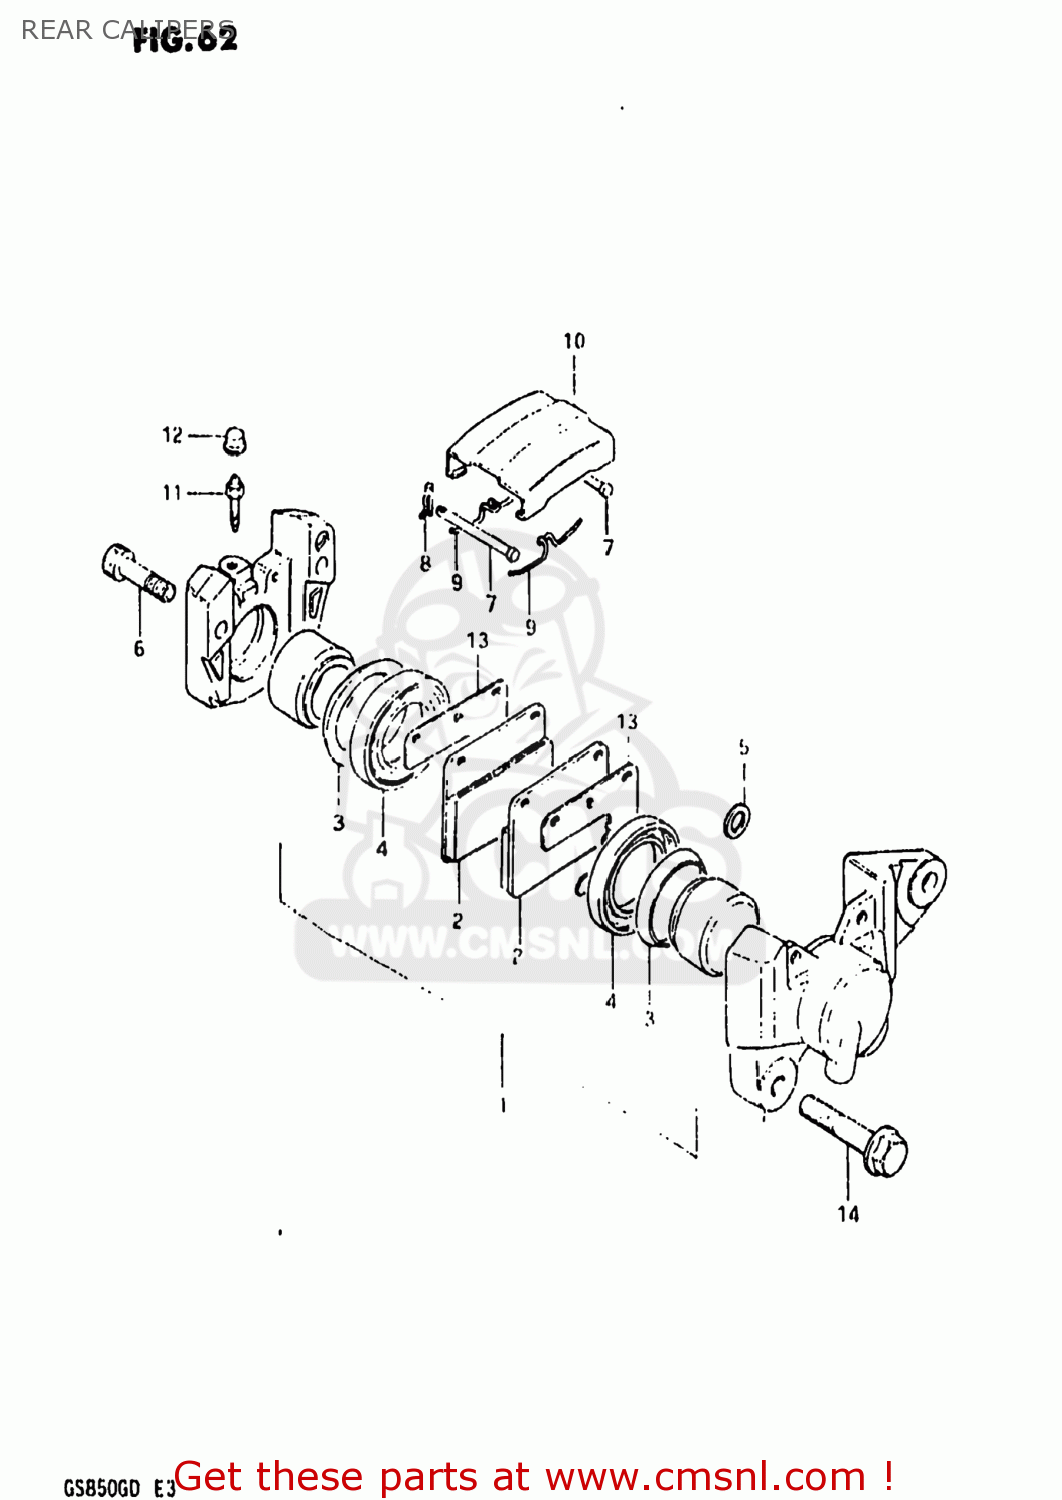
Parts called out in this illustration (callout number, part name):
0	CALIPER ASSEMBLY,REAR
1	PISTON SET
2	PAD,BRAKE
3	SEAL,PISTON
4	BOOT,PISTON
5	SEAL,JOINT
6	BOLT,CALIPER HOUSING
7	PIN,PAD
8	CLIP,PAD PIN
9	SPRING
10	COVER,DUST
11	BLEEDER
12	CAP,BREATHER
13	SHIM,RR CALIPER
14	BOLT
